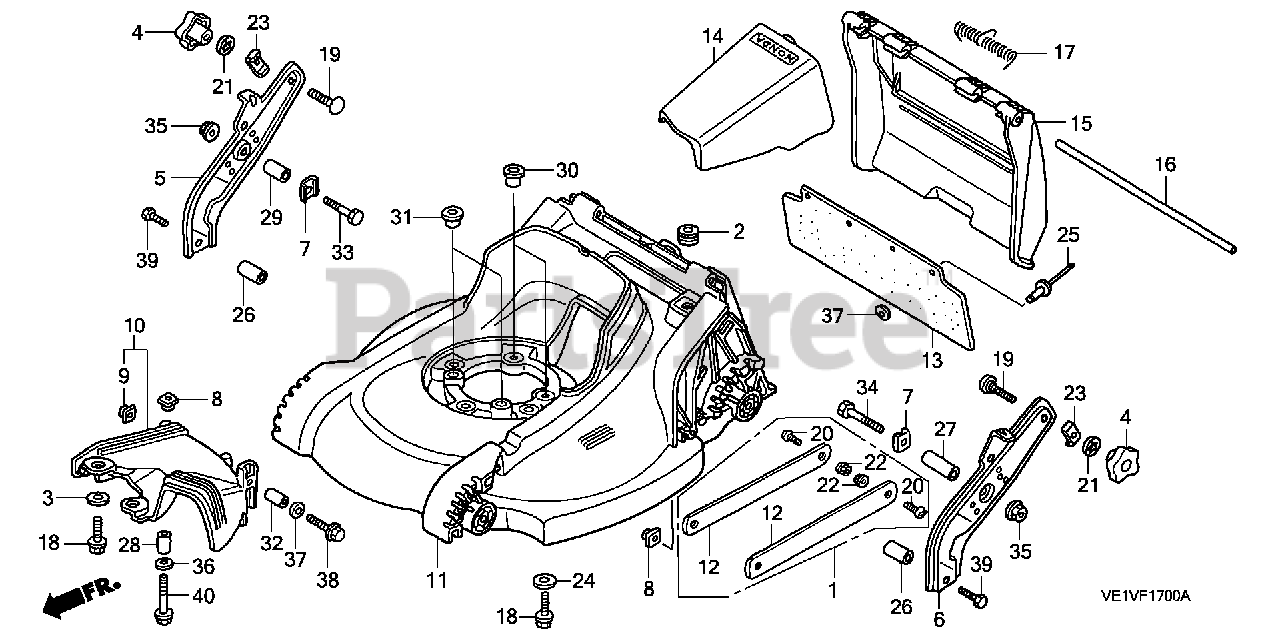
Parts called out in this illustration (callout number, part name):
1	GUARD KIT, HOUSING
2	RUBBER, BATTERY BOX MOUNTING
3	PLATE, HANDLE SETTING
4	GRIP, HANDLE JOINT
5	STAY, R. HANDLE *NH105* (MAT BLACK)
6	STAY, L. HANDLE *NH105* (MAT BLACK)
7	HOLDER, HANDLE STAY
8	NUT, HEADLIGHT SETTING
9	NUT, SPECIAL (6X7)
10	GUIDE ASSY., SCROLL *NH1* (BLACK)
11	HOUSING, CUTTER *NH462* (VINTAGE GRAY SOLID)
12	GUARD, HOUSING (N/A: USE P/N 06761-VE2-000)
13	SHIELD, RR.
14	STUFFING *NH105* (MAT BLACK)
15	GUARD, DISCHARGE
16	SHAFT, DISCHARGE GUARD
17	SPRING, GUARD RETURN
18	BOLT, ENGINE SETTING
19	BOLT, PAN (8X35)
20	SCREW, HOUSING GUARD (N/A: USE P/N 06761-VE2-000)
21	NUT, PUSH (5/16)
22	NUT, FLANGE (N/A: USE P/N 06761-VE2-000)
23	WASHER, FRAME JOINT
24	WASHER, ENGINE MOUNTING
25	RIVET (6MM)
26	COLLAR, STAY (LOWER)
27	COLLAR, L. STAY (UPPER)
28	COLLAR, HANDLE
29	COLLAR, R. STAY (UPPER)
30	COLLAR B, BED
31	COLLAR C, BED
32	COLLAR, SCROLL
33	BOLT, HEX. (8X40)
34	BOLT, HEX. (8X55)
35	NUT, FLANGE (8MM)
36	WASHER, FLAT (8MM)
36	WASHER, PLAIN (8MM)
37	WASHER, PLAIN (6MM)
38	BOLT, FLANGE (6X35)
39	BOLT, FLANGE (8X22)
40	BOLT, FLANGE (8X45)
